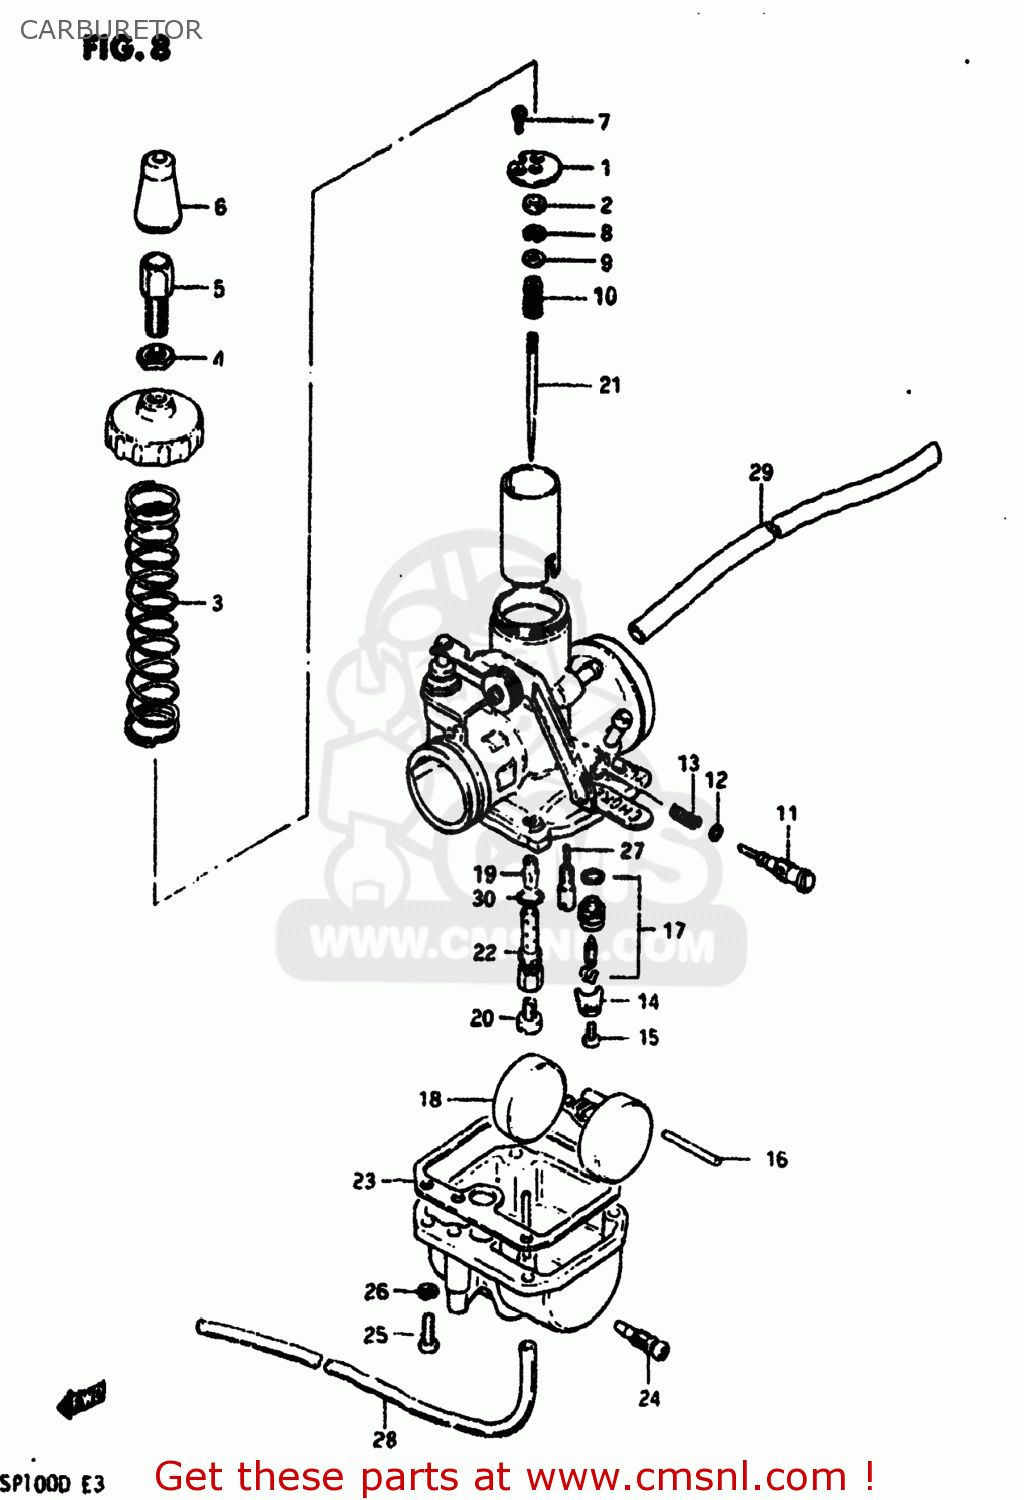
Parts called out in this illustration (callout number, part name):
0	CARBURETOR ASSEMBLY (VM20)
1	PLATE,NEEDLE VALVE FITTING
2	RING
3	SPRING,THROTTLE VALVE
4	NUT
5	ADJUSTER,CABLE
6	CAP,RUBBER
7	SCREW
8	CLIP
9	WASHER,JET NEEDLE
10	SPRING
11	SCREW,THROTTLE STOP
12	O RING
13	SPRING
14	PLATE,NEEDLE VALVE FITING
15	SCREW
16	PIN,FLOAT
17	VALVE ASSEMBLY,NEEDLE
18	FLOAT
19	JET,NEEDLE
20	JET,MAIN(85)
21	NEEDLE JET
22	PIPE,BLEEDER
23	GASKET,FLOAT CHAMBER
24	PLUG,DRAIN
25	SCREW
26	LOCK WASHER
27	JET,PILOT(22.5)
28	HOSE
29	HOSE
30	O RING
31	(CA) VALVE,THROTTLE
